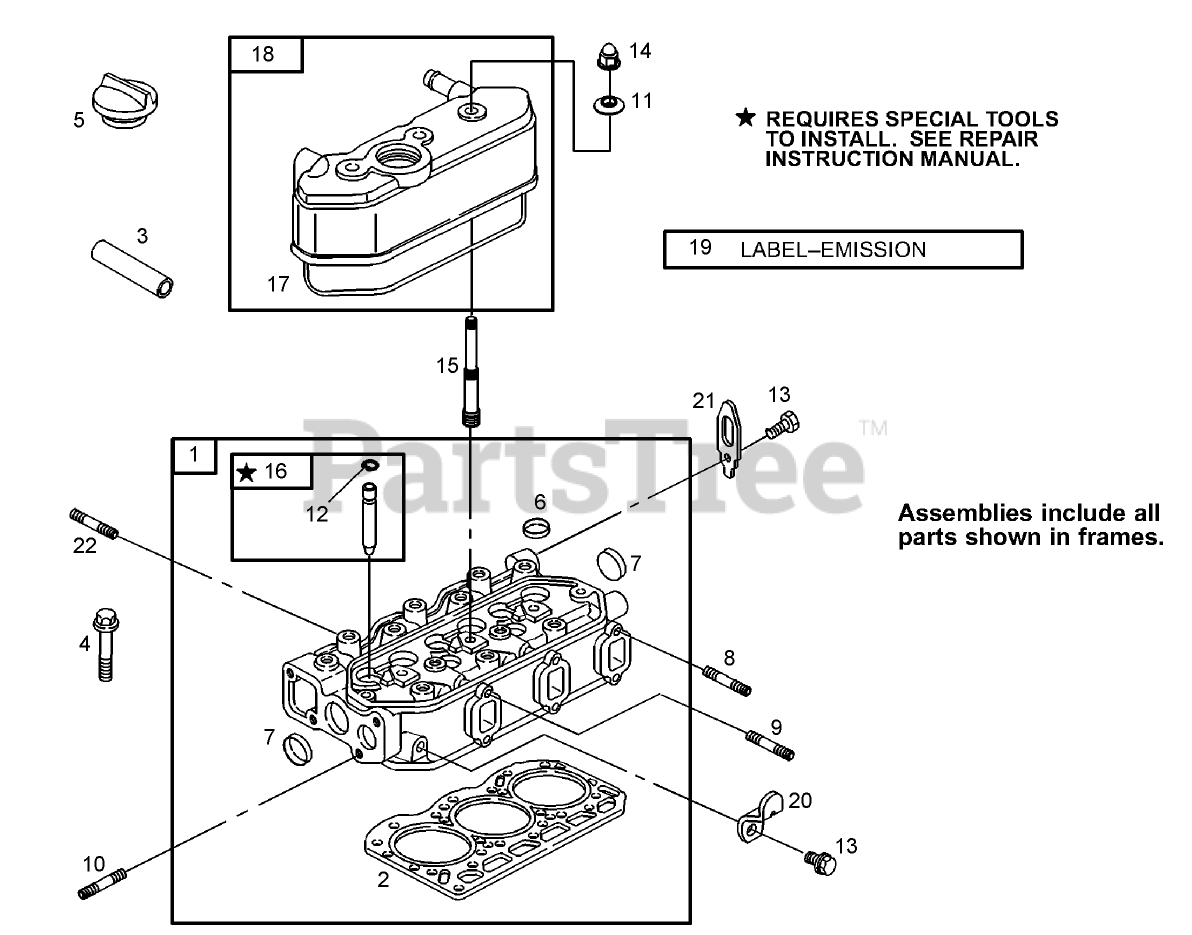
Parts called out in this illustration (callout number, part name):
2	GASKET-HEAD, CYLINDER
3	TUBE-BREATHER
4	SCREW-METRIC
5	CAP-FILL, OIL
6	PLUG-WELCH
7	PLUG-WELCH
8	STUD-METRIC
9	STUD-METRIC
10	STUD-METRIC
11	WASHER-SEAL
12	RETAINER
13	SCREW-HEX
14	NUT-HEX, METRIC
15	STUD-ARM, ROCKER
16	BUSHING-GUIDE
17	GASKET-COVER, ROCKER
18	COVER-ROCKER
19	EMMISION LABEL KIT
20	BRACKET-LIFTING
21	BRACKET-LIFTING
22	STUD-METRIC
